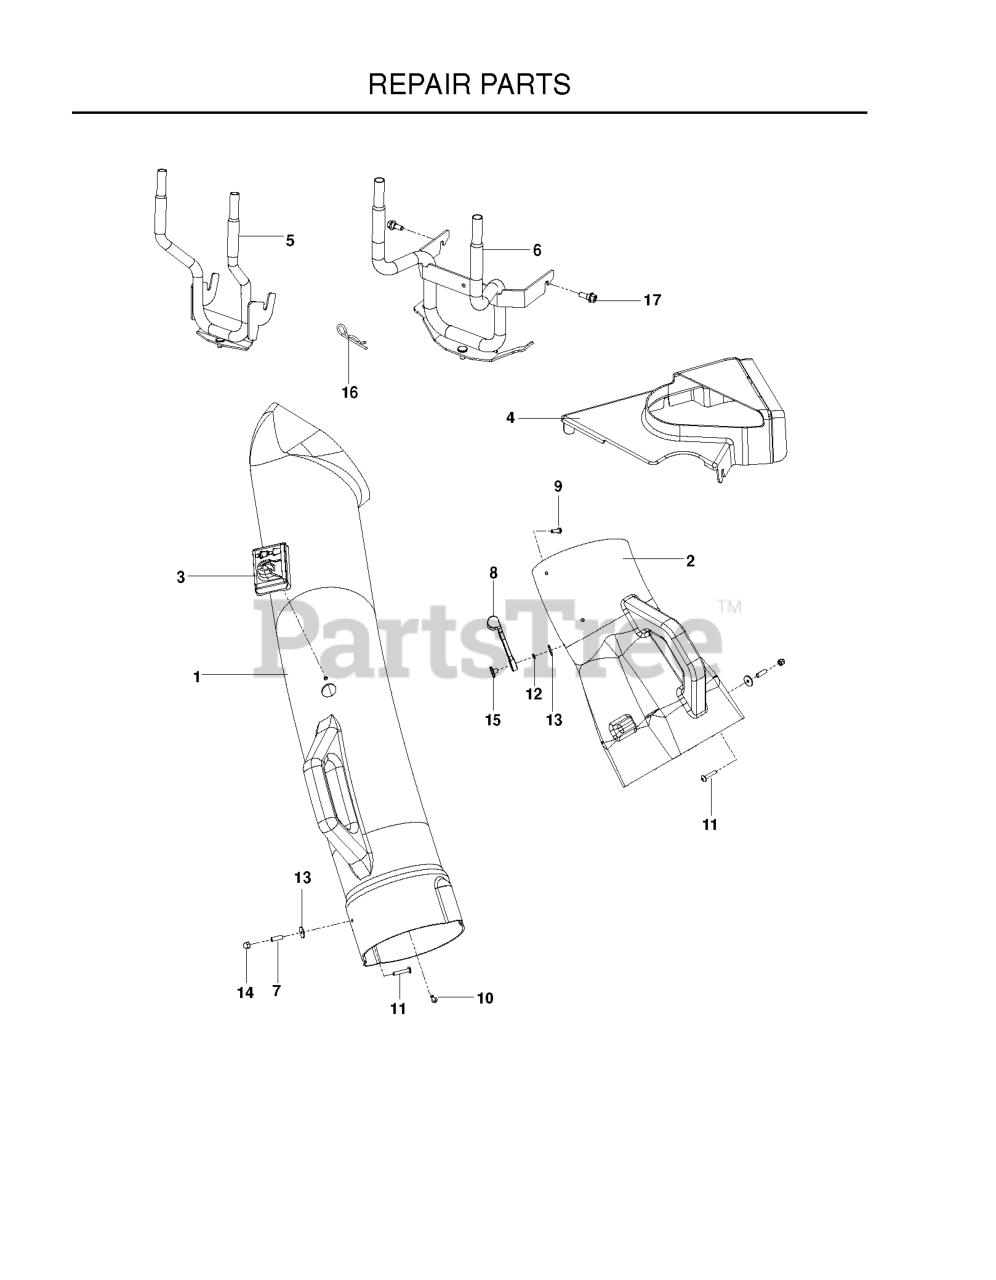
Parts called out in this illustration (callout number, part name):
1	CHUTE, UPPER - TRIMMED
2	CHUTE, MIDDLE - TRIMMED
3	DUMP BAG INDICATOR
4	SHIELD, BELT, 48
5	BAGGER.ASM.SUPPORT.GT.TEX.BLAC
6	BRACKET.BAGGER.3-BIN.BLACK
7	BSHG .202X.75 LG SPLIT ZD SPEC
8	HOOD LATCH
9	SCREW #10-24 X 5/8
10	SCREW
11	SCREW #10-24 X 1-1/8 ZD SPEC
12	WASHER - 3/16 LOCK ZD
14	NUT 10-24 ACORN ZD
15	NUT 10-24 WELD PLATED
16	HAIRPIN #4
17	SHOULDER BOLT, SELF-TAP
